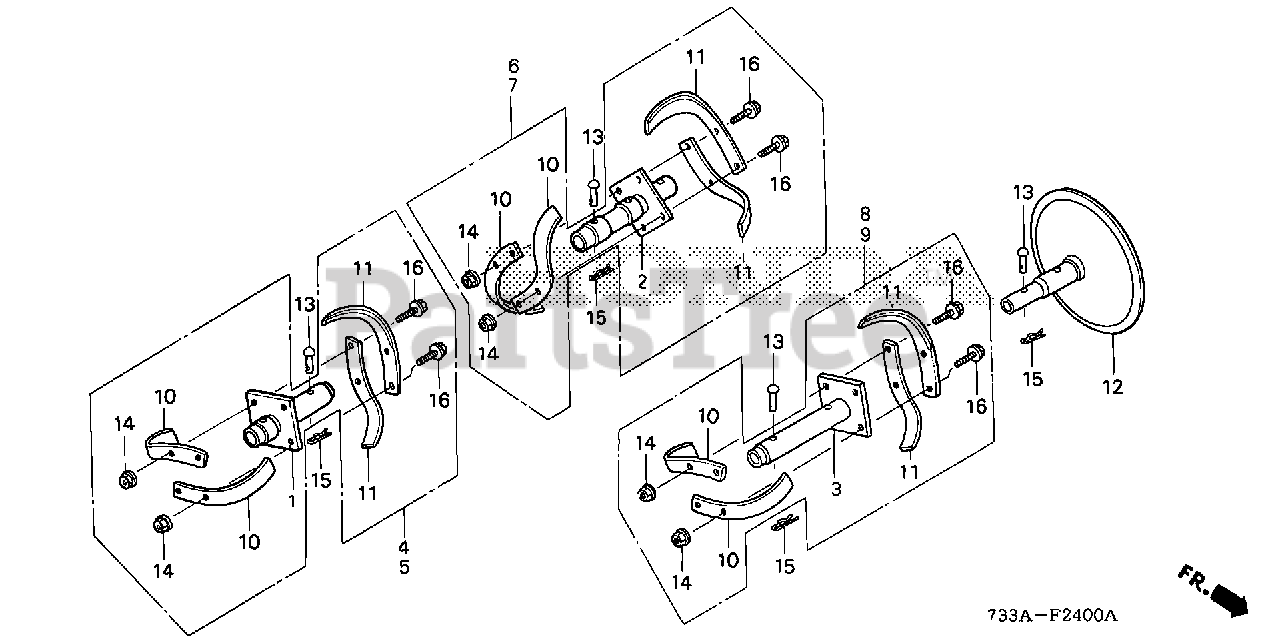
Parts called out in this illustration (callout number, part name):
1	PIPE (INNER)
1	PIPE (INNER) (NOT AVAILABLE)
2	PIPE, R. (OUTER)
3	PIPE, EXTENSION
4	ROTOR ASSY., R. (INNER) (NOT AVAILABLE)
4	ROTOR ASSY., R. (INNER)
5	ROTOR ASSY., L. (INNER) (NOT AVAILABLE)
6	ROTOR ASSY., R. (OUTER)
7	ROTOR ASSY., L. (OUTER)
8	ROTOR ASSY., R. EXTENSION
9	ROTOR ASSY., L. EXTENSION
10	TINE A, ROTARY
11	TINE B, ROTARY
12	DISK, SIDE
13	PIN (10X53.5)
14	NUT, FLANGE (10MM)
15	PIN, LOCK (10MM)
16	BOLT, FLANGE (10X25)
